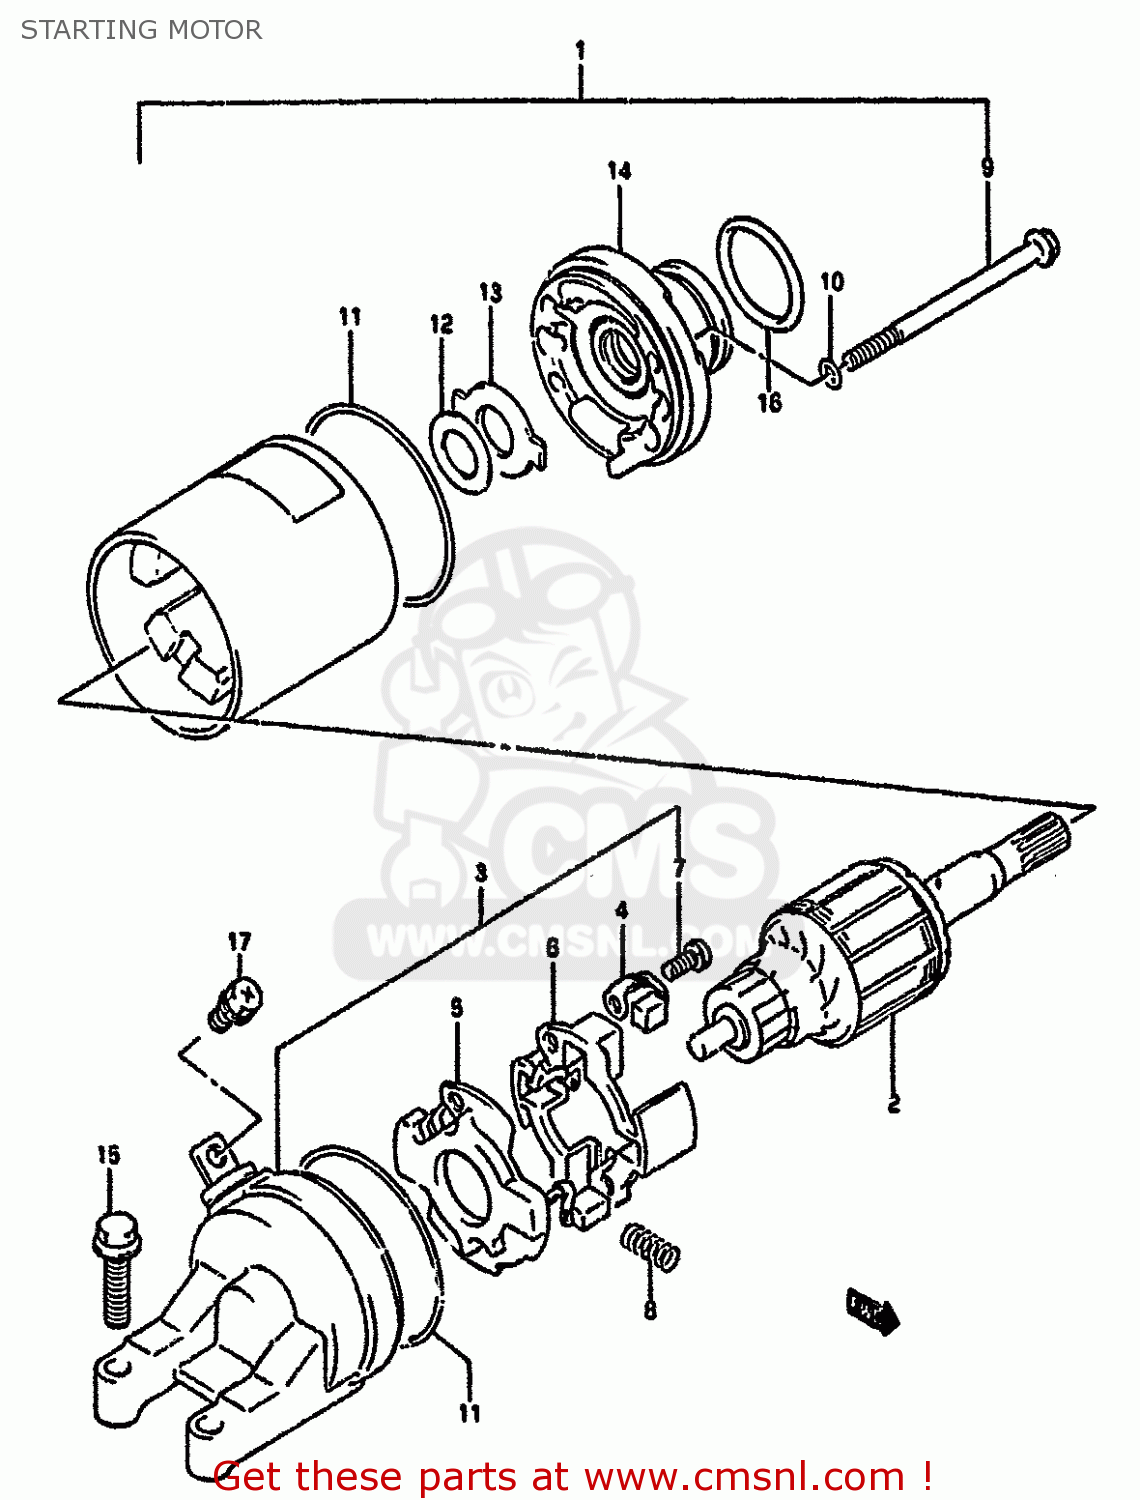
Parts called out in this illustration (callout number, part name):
1	MOTOR ASSEMBLY,STARTING
2	ARMATURE
3	FRAME ASSEMBLY,COMMUTATOR
4	BRUSH
5	BRUSH SUB ASSEMBLY
6	HOLDER,BRUSH
7	SCREW
8	SPRING
9	BOLT
10	O RING
11	O RING
12	SHIM
13	PLATE,LOCK
14	BRACKET
15	BOLT(6X23)
16	O RING(D:3,ID:24.5)
17	SCREW(5X8)
